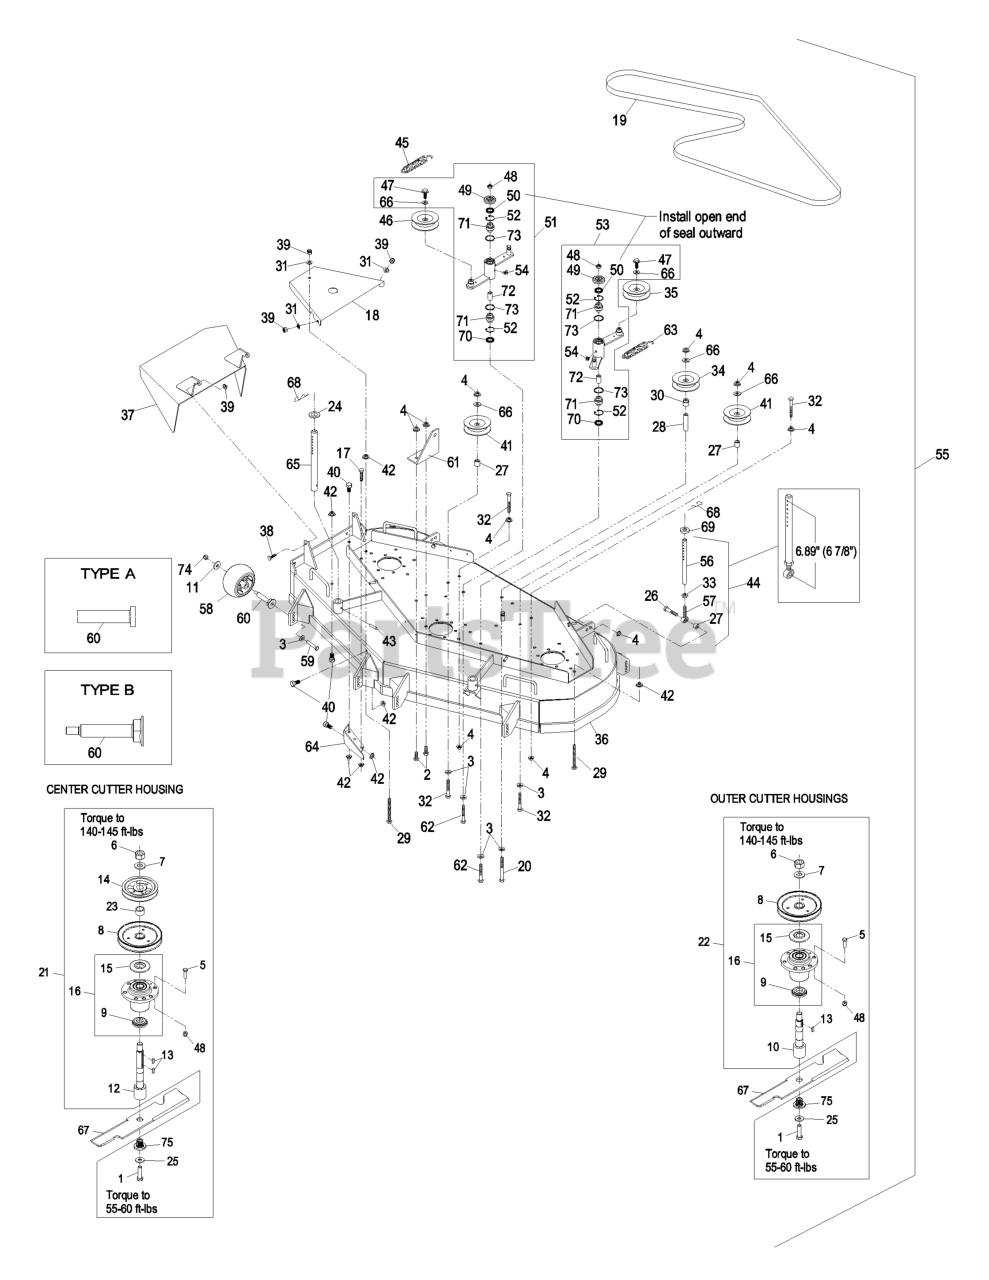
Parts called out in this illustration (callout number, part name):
1	SCREW-HH
2	SCREW-HH
3	WASHER-BELLEVILLE
4	NUT-HHF, WHIZ
5	SCREW-HH
6	NUT-HH
8	SHEAVE,BLADE DRIVE 6.30
9	SPACER-GUARD, BOTTOM
10	KIT, SPLINED SPINDLE 103-
12	KIT, SPLINED SPINDLE 103-
14	SHEAVE,MOWER DRIVE
15	GUARD-BEARING, TOP
16	KIT, CUTTER HOUSING
17	SCREW-HH
18	SHIELD,BELT SIDE FMD524
19	BELT,BLADE DRIVE FMD524
20	SCREW-HH
21	ASM,CUTTER HSG FMD524 CTR
22	ASM, CUTTER HSG COMPLETE
23	SPACER,TUBE
24	SPACER-DECK SUPPORT
25	WASHER-SPRING
26	SCREW-HH
28	SPACER-ANCHOR, CLUTCH
29	BOLT,TAP HH
30	BUSHING,IDLER
31	WASHER-FLAT
32	BOLT-CARR
33	NUT-HEX
34	PULLEY-IDLER
35	PULLEY-IDLER
37	WLD,CHUTE FMD524
38	SCREW-HH
39	NUT-LOCK, NI
40	SCREW-HH
41	IDLER,PULLEY
45	SPRING-EXTENSION
46	IDLER,PULLEY
47	SCREW-HHF
48	NUT-LOCK, NI
49	GUARD-TOP
50	SEAL-LIP, SINGLE
51	KIT, IDLER ARM W/BEARINGS
52	RING-SNAP
53	KIT, IDLER ARM W/BEARINGS
54	FITTING-GREASE, 90 DEG
55	Complete Deck Assembly
56	LINK,SUPPORT
57	BALLJOINT
58	ROLLER-SCALP, ANTI
59	SCREW-HH
60	BUSHING-ROLLER
61	BRACKET,SPRING ANCHOR
62	SCREW-HH
63	SPRING-EXTENSION
64	WLD,BAFFLE DISCHARGE
65	ROD,DECK SUPPORT
66	WASHER-FLAT
68	PIN,HAIR COTTER
70	SEAL-LIP, DOUBLE
71	BEARING-SPHERICAL
72	BUSHING-LEVER, LIFT
74	NUT-HHF, WHIZ
75	BUSHING,SPLINED
